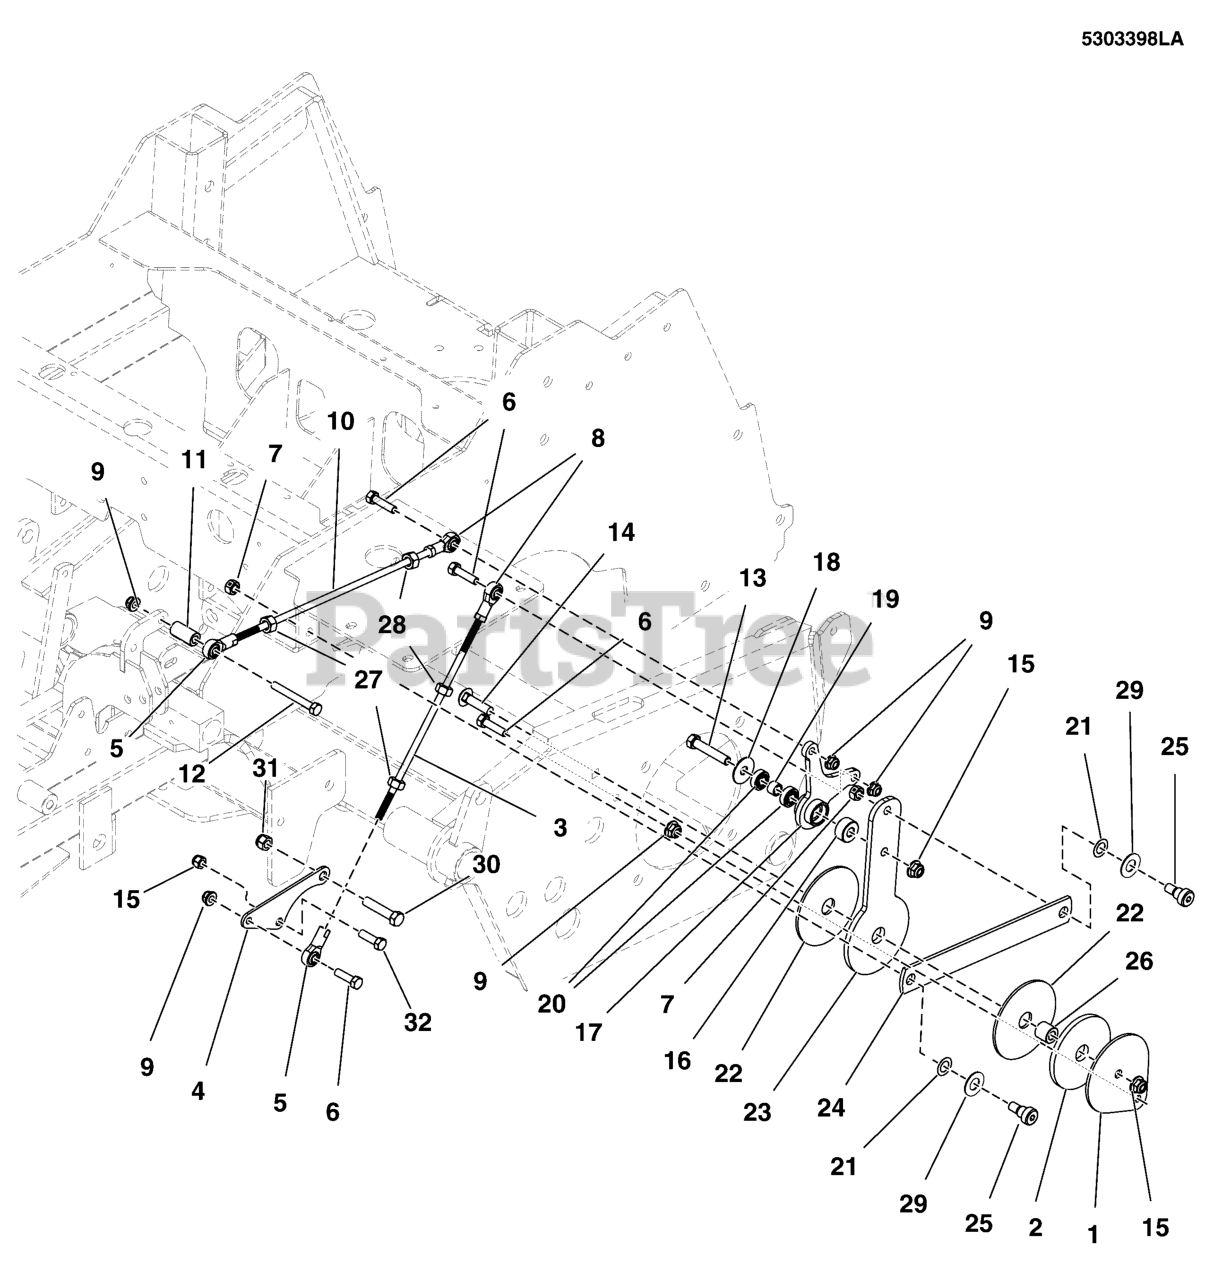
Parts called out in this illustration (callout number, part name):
1	PLATE, CONTROL SYSTEM LOCK - BLK
2	PAD, .77 X 3.50 X .25, POLYURETHANE
3	ROD, 5/16-24 RH & LH, 8.75" CZ
4	PLATE, CONTROL MOUNT - BLK
5	BALL JOINT 5/16-24 RH FEMALE BRONZE RACE
6	BOLT, 5/16-18 X 1-1/4" GD5 YZ
7	NUT, Hex, Side Lock, 3/8-16
8	BALL JOINT 5/16-24 LH FEMALE BRONZE RACE
9	NUT, 5/16-18 HEX NYLOCK FLANGE NUT
10	ROD, HYDRO LINKAGE, 14.63
11	SPACER, .38 X .75 X 1.25, PM, CZ
12	BOLT, 5/16-18 X 2-1/2" GD5 YZ
13	BOLT, 3/8-16 X 2-1/2" GD5 CZ
14	BOLT, 3/8-16 X 1-1/2, CARRIAGE, GD5, CZ
15	NUT, 3/8 - 16 HEX NYLOCK FLANGE
16	SPACER, .39 X 1.00 X .50, PM, CZ
17	PIVOT, CONTROL SYSTEM, S125XT
18	WASHER, 3/8" Fender
19	SPACER, .39 X .55 X .38, PM, CZ
20	BEARING, .375" ID X .875" OD X .341" THK
21	WAVE WASHER, 1/2"ID X 087"OD X .01 THK.
22	PAD, CONTROL SYSTEM
23	PLATE, CONTROL SYSTEM ARM - HT
24	LINK, CONTROL SYSTEM ARM, IS2100 - BLK
25	BOLT, 3/8-16 X 3/8", 1/2" SHOULDER
26	SPACER, .39 X .75 X .69, PM, CZ
27	NUT, Hex, 5/16-24
28	NUT, 5/16-24 HEX, LH
29	WASHER, 1/2" GD9 YZ
30	BOLT, 7/16-14 X 3/4, GD 5 YZ
31	NUT, 7/16-14 HEX TOP LOCK
32	BOLT, 3/8-16 X 1" GD5 CZ
